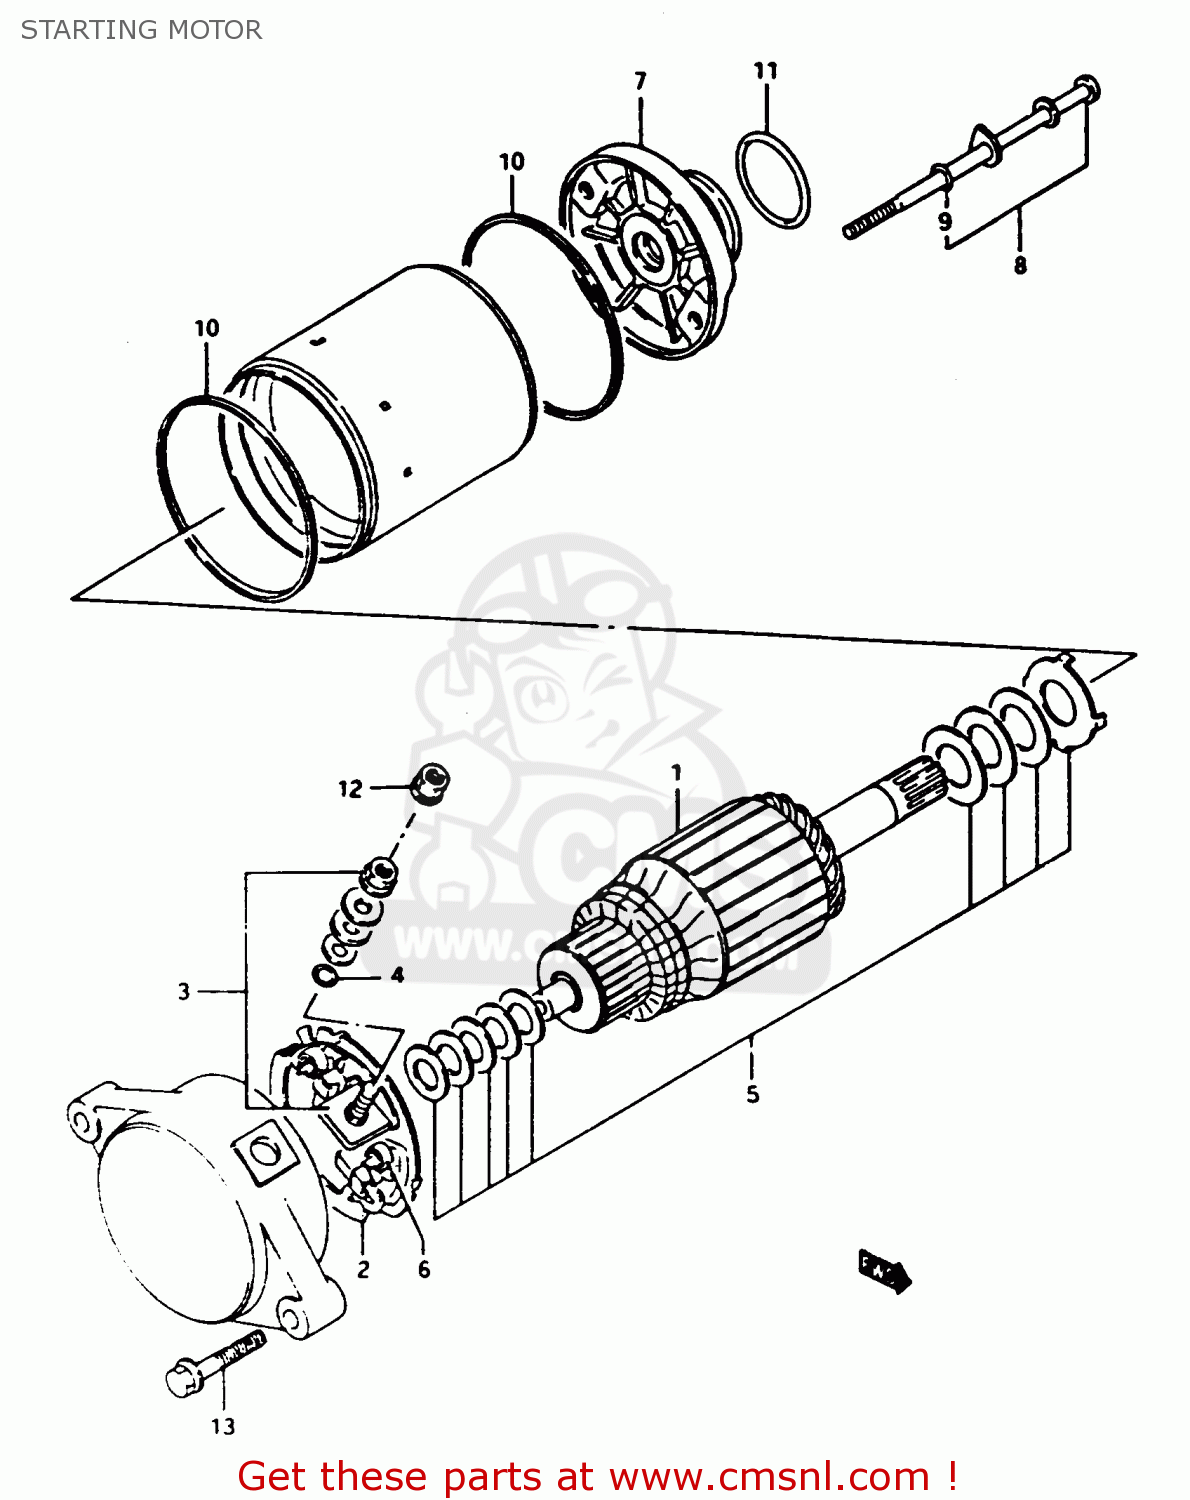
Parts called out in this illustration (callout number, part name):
1	ARMATURE
2	HOLDER SET,BRUSH
3	TERMINAL SET,BRUSH,PLUS
4	O RING
5	SHIM SET,STARTING MOTOR
6	SPRING,BRUSH
7	BRACKET ASSY,FR
8	BOLT SET,STARTING MOTOR
9	O RING
10	O RING
11	O RING(D:3,ID:24.5)
12	NUT
13	SCREW
